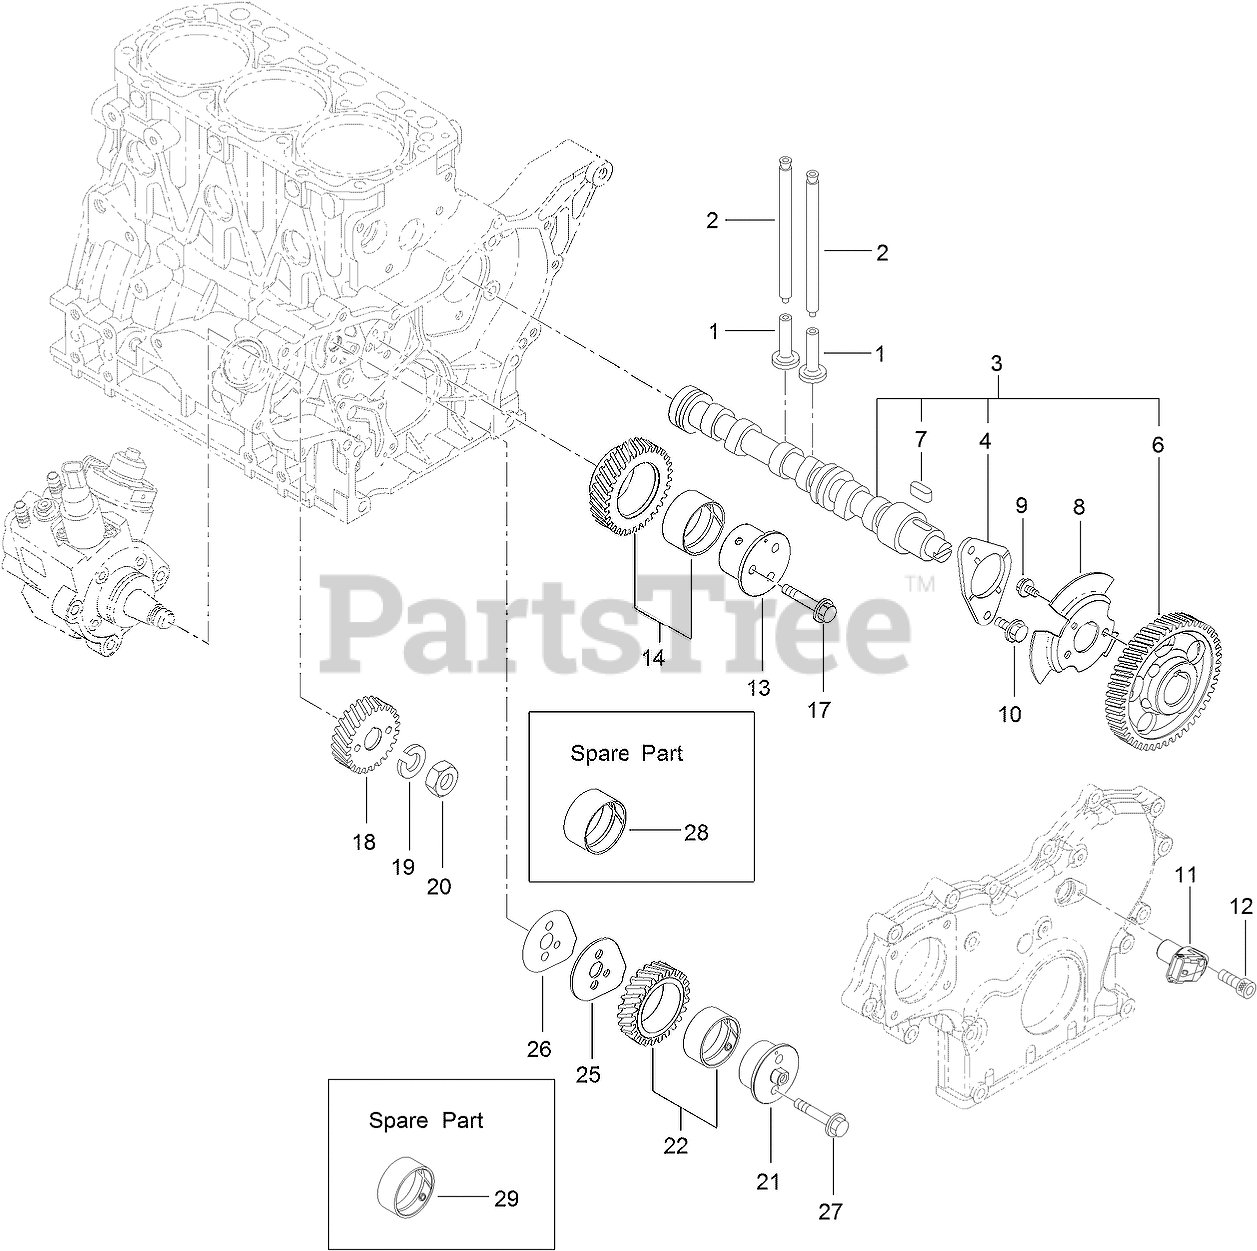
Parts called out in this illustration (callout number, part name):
2	ROD-PUSH
3	CAMSHAFT ASM
4	METAL-THRUST
6	Gear-Camshaft
8	PULSER-CAMSHAFT
11	SENSOR-REV, GEAR
13	Shaft-Idle, Gear A
14	IDLE GEAR A ASM
18	Gear-Pump, Supply
19	Washer-Spring
20	Nut-Lock
21	Shaft-Idle, Gear B
22	IDLE GEAR B ASM
25	Plate-Idle, Shaft
26	Gasket-Idle, Shaft B
28	BUSHING
29	BUSHING
